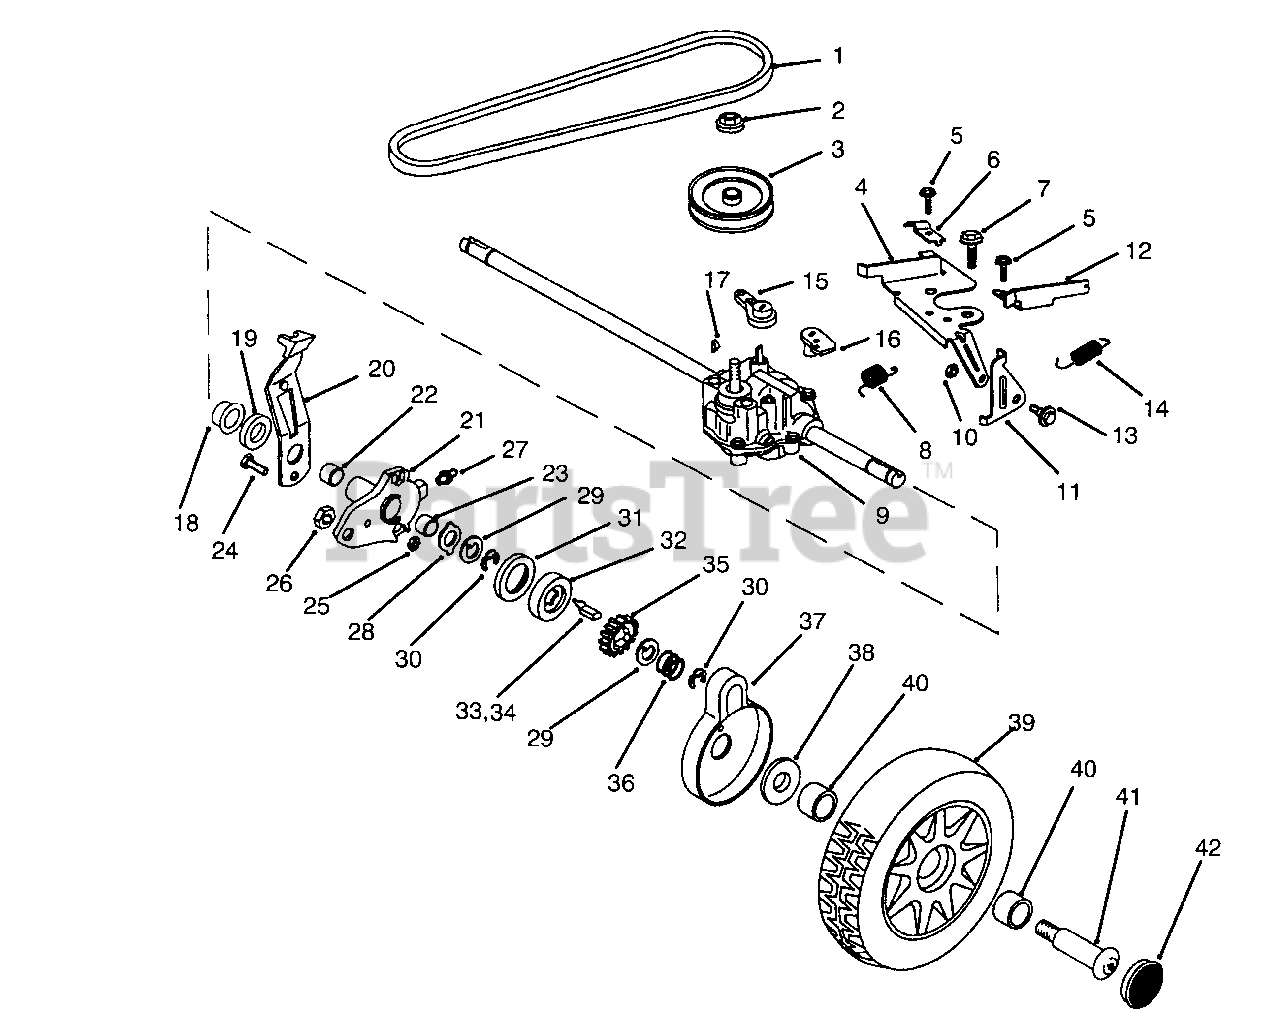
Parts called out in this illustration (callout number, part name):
2	Nut-Lock
3	Pulley-Transmission
4	Plate-Actuator
7	Screw-Plate to Trans.
9	Transmission
10	Nut-Lock
11	Arm-Trans. Engagement
12	Guide-Belt
13	Bolt-Shoulder
14	Spring-Extension
15	Arm-Shift
16	Arm-Clutch
18	Ring-Isolator
20	Assembly-Knob & Spring
21	Pivot Arm Assy. (Incl. Ref. No. 22-23 & 27)
25	Nut-Lock
26	Nut-Jam
27	Fitting-Grease
28	Washer-Inner Thrust
29	Washer-Keyed
30	Ring-Retaining
31	Ring-Friction
32	Washer-Clutch
34	Key, Rocking-L.H.
35	Gear-Pinion 15T
36	Spring-Compression
37	Cover-Wheel
38	Washer-Stepped
39	Assembly-Wheel (Incl. Ref. No.40)
41	Bolt-Wheel
